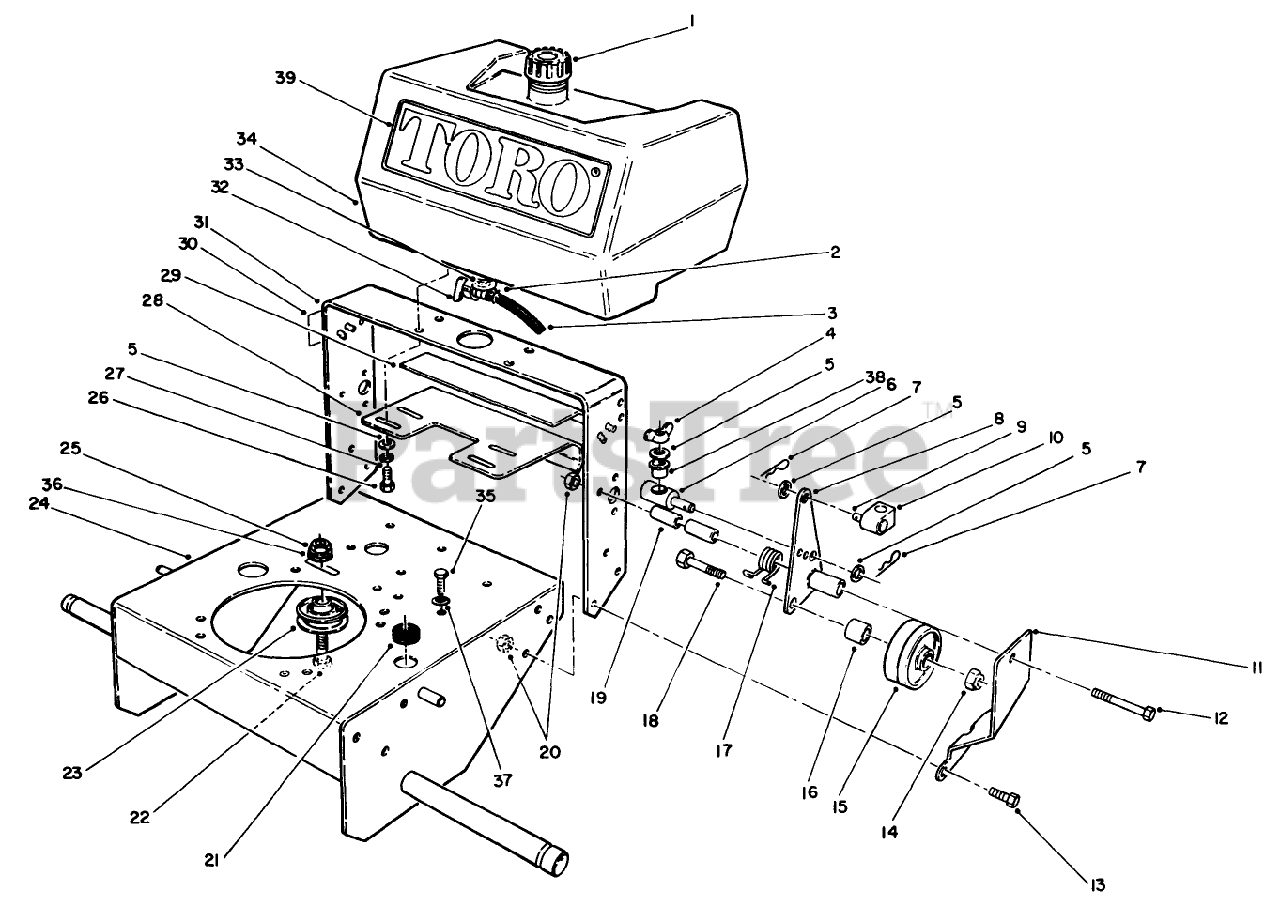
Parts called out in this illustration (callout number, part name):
1	GAS CAP ASM
4	NUT-WING
5	WASHER-PLAIN
6	FITTING-ROD
9	PIN-CLEVIS
10	FITTING-ROD
12	SCREW-HH
13	SCREW-HH
14	NUT-LOCK, NI
16	WHEEL IDLER SPACER
17	SPRING-TORSION, LH
18	SCREW-LEVELER
19	SPACER-PIVOT, IDLER
20	NUT-LOCK, NI
21	GROMMET
22	SCREW-HH
23	PULLEY-IDLER
24	FRAME *R
25	NUT-HF
26	SCREW-HH
27	WASHER-LOCK
30	DECAL - FUEL SHUT OFF
32	FUEL VALVE
33	O-RING
34	FUEL TANK
35	SCREW
36	WASHER-FLAT
37	WASHER-LOCK/EXT
38	BUSHING-NYLON
